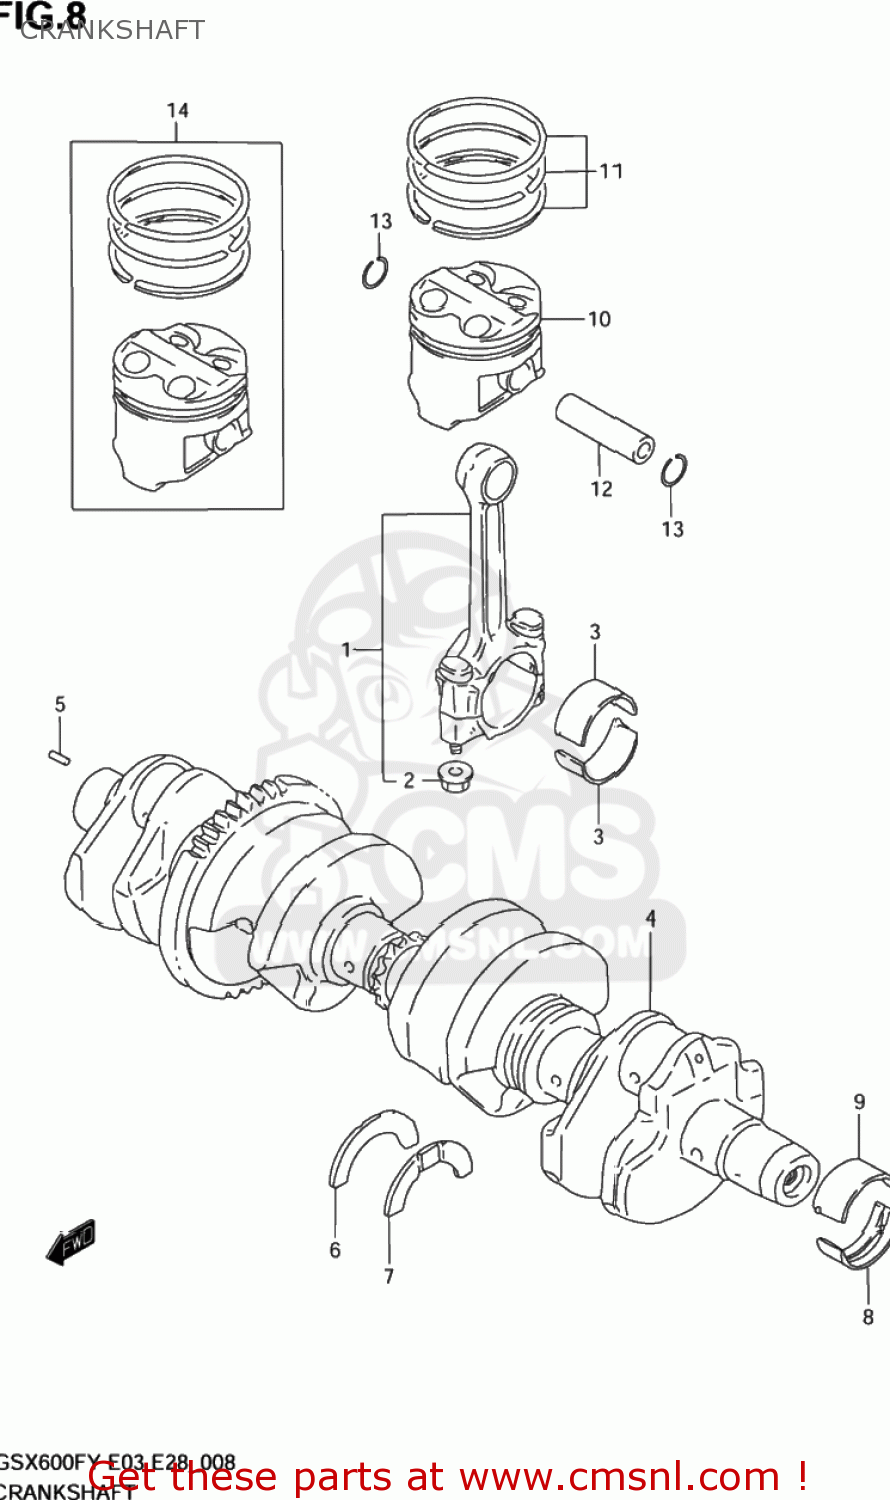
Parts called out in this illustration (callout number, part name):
1	CONNECTING ROD ASSY
2	NUT
3	BEARING,CRANK PIN
4	CRANKSHAFT SET
5	PIN
6	PLATE,CRANK THRUST
7	PLATE,CRANK THRUST
8	BEARING,CRANKSHAFT LWR
9	BEARING,CRANKSHAFT UPR
10	PISTON
11	RING SET,PISTON
12	PIN,PISTON
13	CIRCLIP
14	PISTON SET(OS:0.5)
